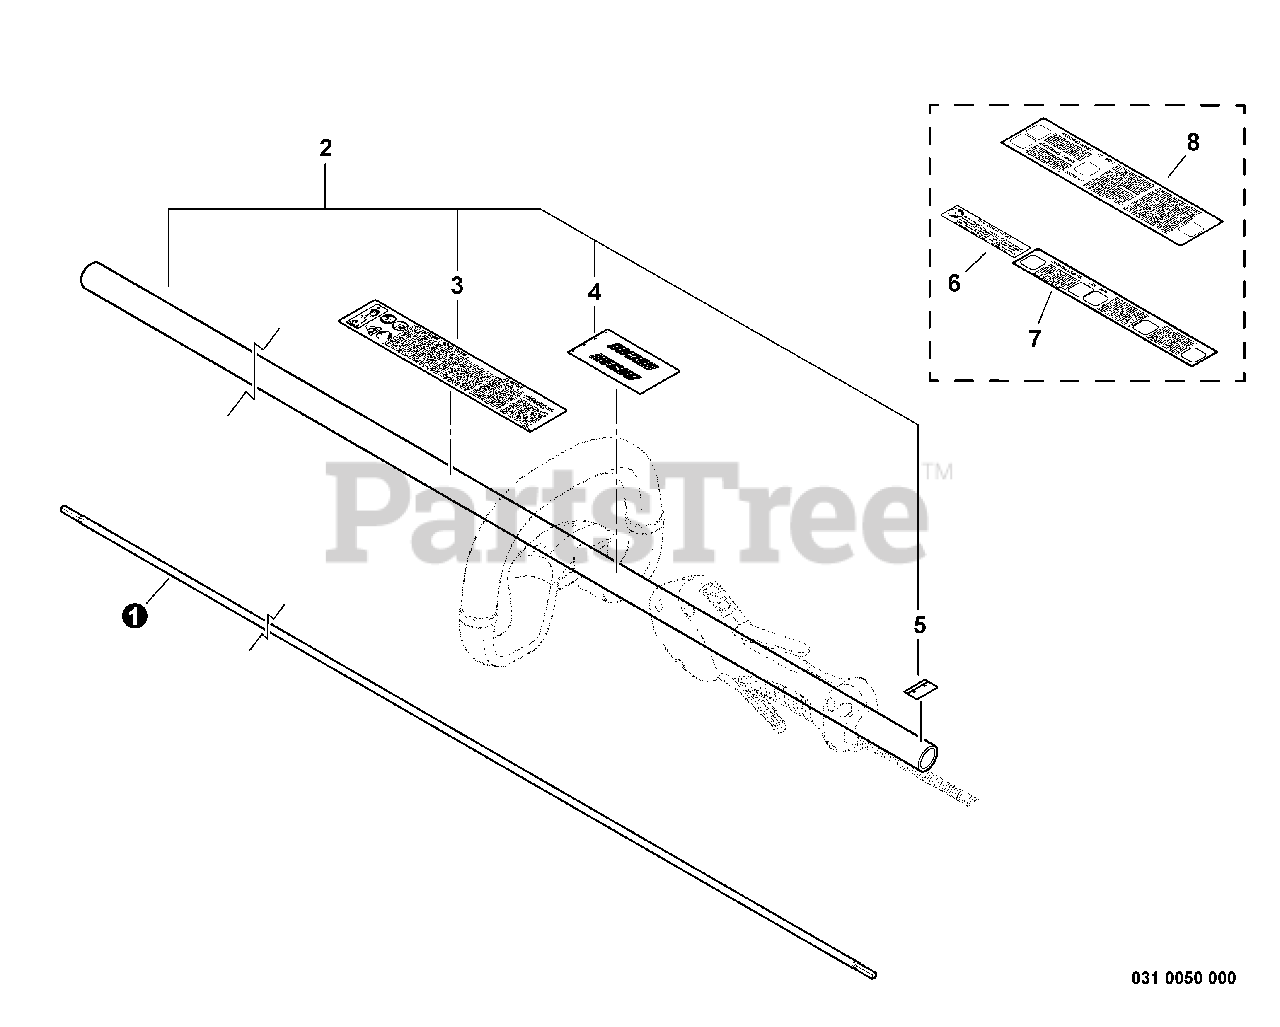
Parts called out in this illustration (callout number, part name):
1	DRIVESHAFT - SOLID
2	MAIN PIPE ASSY
3	LABEL - CAUTION -- SPANISH
4	LABEL - HANDLE LOCATION
5	LABEL - ALIGNMENT
6	LABEL - CAUTION -- SPANISH
7	LABEL - CAUTION -- SPANISH
8	LABEL - CAUTION -- SPANISH
